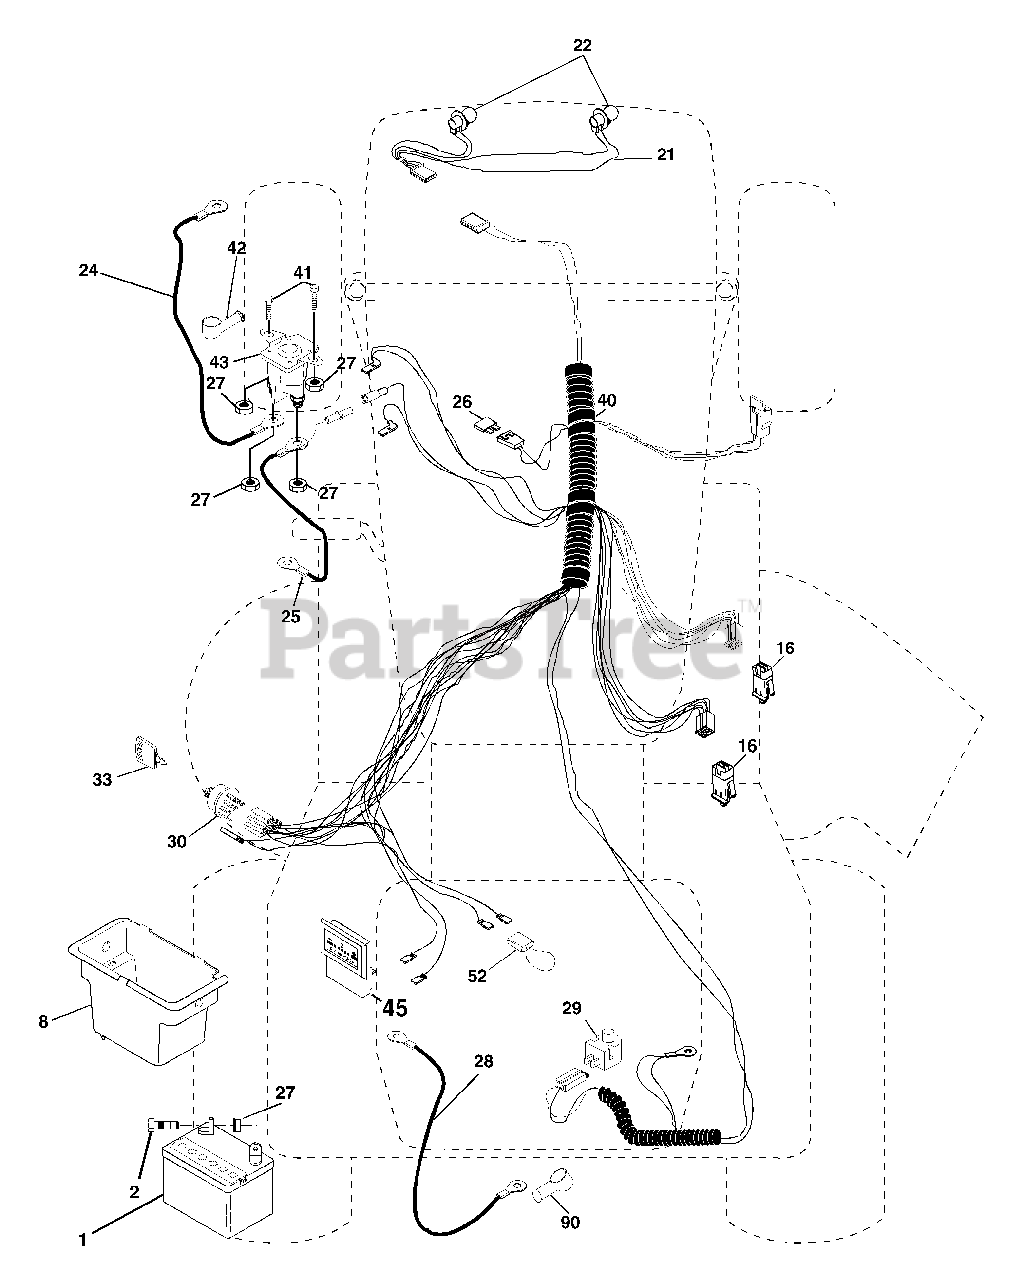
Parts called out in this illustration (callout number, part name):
1	Battery
2	Bolt Hex Hd 1/4-20unc X 3/4
8	Box Battery Fender
16	Switch Interlock
21	Harness Asm Light W/4152J
22	Bulb Light
24	Cable Battery 6 Ga 11" red
25	Cable Battery 6 Ga w/16 wire, red
26	Fuse 20 AMP
27	Nut Keps Hex 1/4-20 unc
28	Cable Ground 6 Ga 12" black
29	Switch Plunger Nc Gray
30	Switch Ign
33	Key Ign
40	Harness Ign
41	Bolt Blk Fin Hex 1/4-20 X 1/2
42	Cover Terminal Red
43	Solenoid
45	Ammeter
52	Protection Wire Loop
89	Cover Terminal Battery
